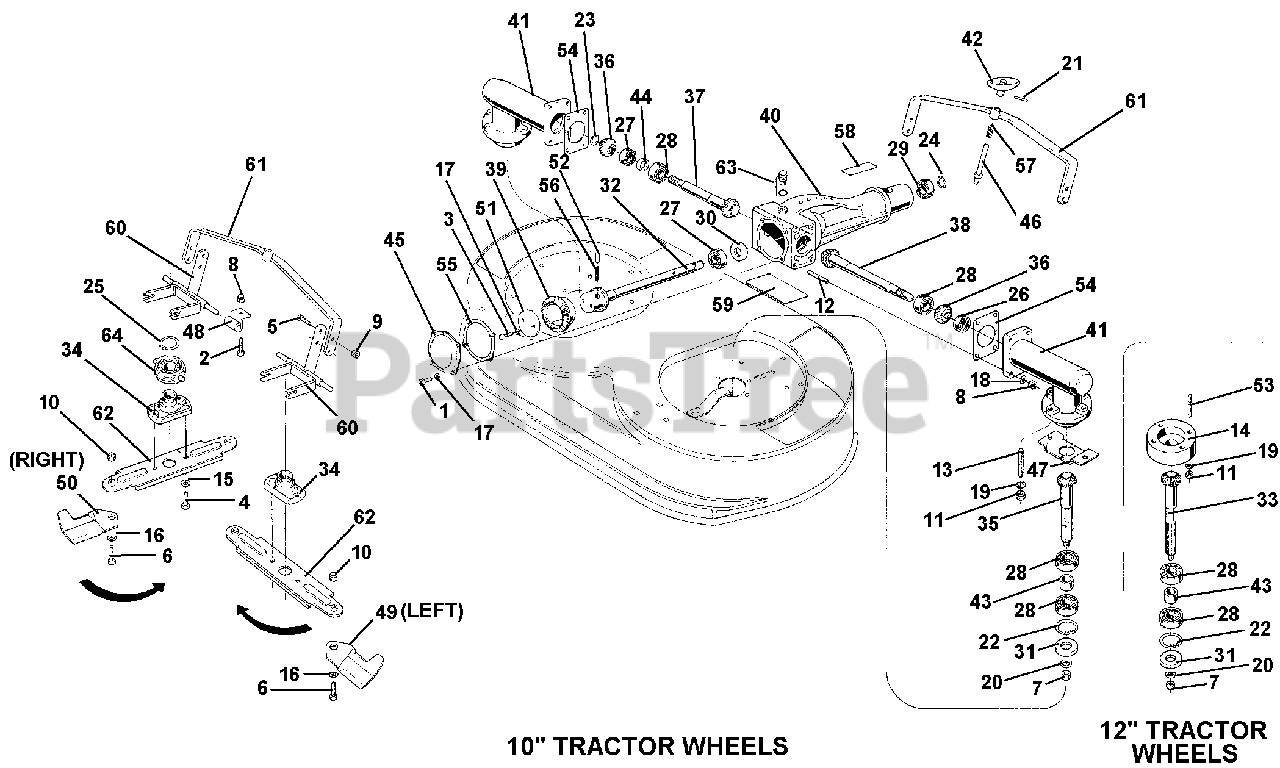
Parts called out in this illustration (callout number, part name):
1	SCREW TE M6 X 14
2	SCREW M8 X 16
3	SCREW M6 X 12
4	SCREW M8 X 14
5	SCREW M8 X 20
6	SCREW M10 X 30
7	NUT,LOW M12
8	NUT, SELF LOCKING M8
10	NUT, SELF LOCKING M10
11	NUT, SELF LOCKING M10 LOW
12	STUD M8 X 40 X 14 X 14
13	STUD M10 X 37 X 19 X 15 8G
14	STUD M10 X 68 X 34 X 15
15	SUPER WASHER 8 DIN 6796
16	SUPER WASHER 10 DIN 6796
17	WASHER, LOCK 6.4
18	WASHER, LOCK 8.4
19	WASHER, LOCK 10.5
20	WASHER, LOCK 13
21	LOCKING PIN 4 X 20 SPIRAL
22	CIRCLIP, INTERN D 52
23	OUTSIDE CIRCLIP
24	CIRCLIP EXTERN. D 20
25	EXT. CIRCLIP D 35
26	BEARING 17 X 40 X 12 6203
27	BEARING 20 X 47 X 14 6204
28	BEARING 25 X 52 X 15 6205
29	BEARING 20 X 47 X 14 6204 2RS ST
30	SEAL, 0IL 20 X 42 X 7 STANDARD
31	OIL SEAL 25 X 52 X 7
32	PROPELLER SHAFT
33	BEVEL PINION
34	BLADE HOLDER HUB
35	BEVEL PINION
39	RING BEVEL GEAR
40	CENTRAL BODY OF 2 BLADES L.M.
41	SIDE BODY OF 2 BL. LAWN MOWER
43	SPACER 25 X 30 X 24
46	SELECTOR PIN
51	DISC, GEAR LOCKING
53	CRANKCASE SPACER
54	SIDE GASKET
56	STOP LEVER SPRING
57	FERRULE SPRING
58	TRANSFER FOR LAWN MOWER
60	ADJUSTING LEVER
62	BLADE HOLDER
63	BREATHER CAP 1/4 GAS
